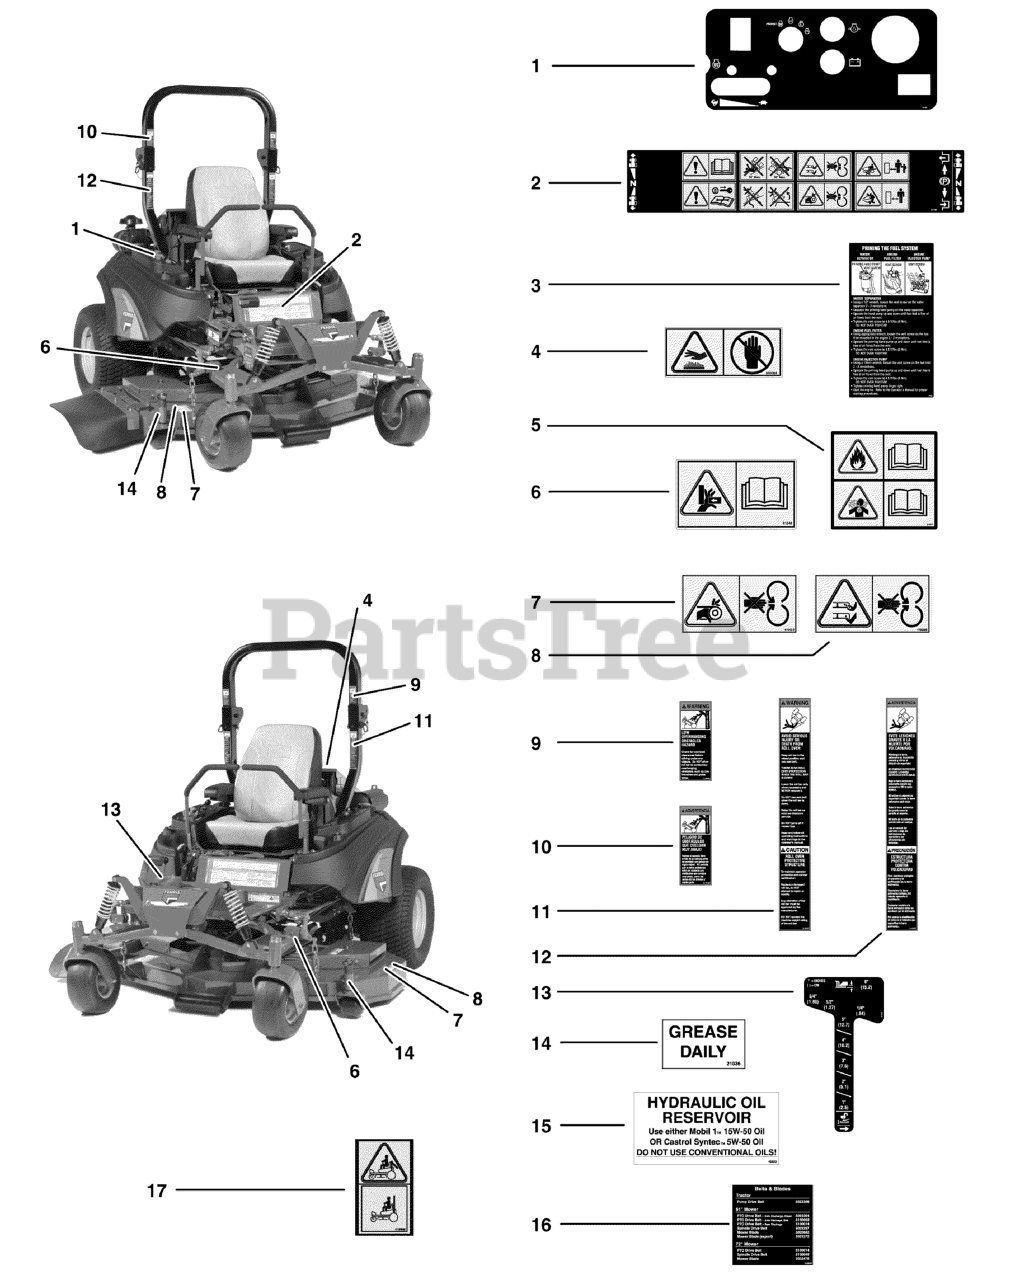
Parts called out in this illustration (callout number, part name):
1	DECAL, CONTROL PANEL, DIESEL
2	DECAL, MAIN, CE
3	DECAL, PRIMING INSTRUCTIONS
4	DECAL-HOT- HAND IN FLAME
5	DECAL, DANGER, CE, OPEN FLAME
6	DECAL, PINCH POINT, CE
7	DECAL, CE DANGER, HAND IN BELT
8	DECAL-DANGER ROTATING BLADE SYMBOLS
9	DECAL, WARNING, OVERHANG, ROPS
13	DECAL, HEIGHT OF CUT
14	DECAL, GREASE DAILY
15	DECAL, OIL RESERVOIR
16	DECAL, BELT & BLADE, IS4500Z
17	DECAL, WARNING, ROLL BAE, CE
